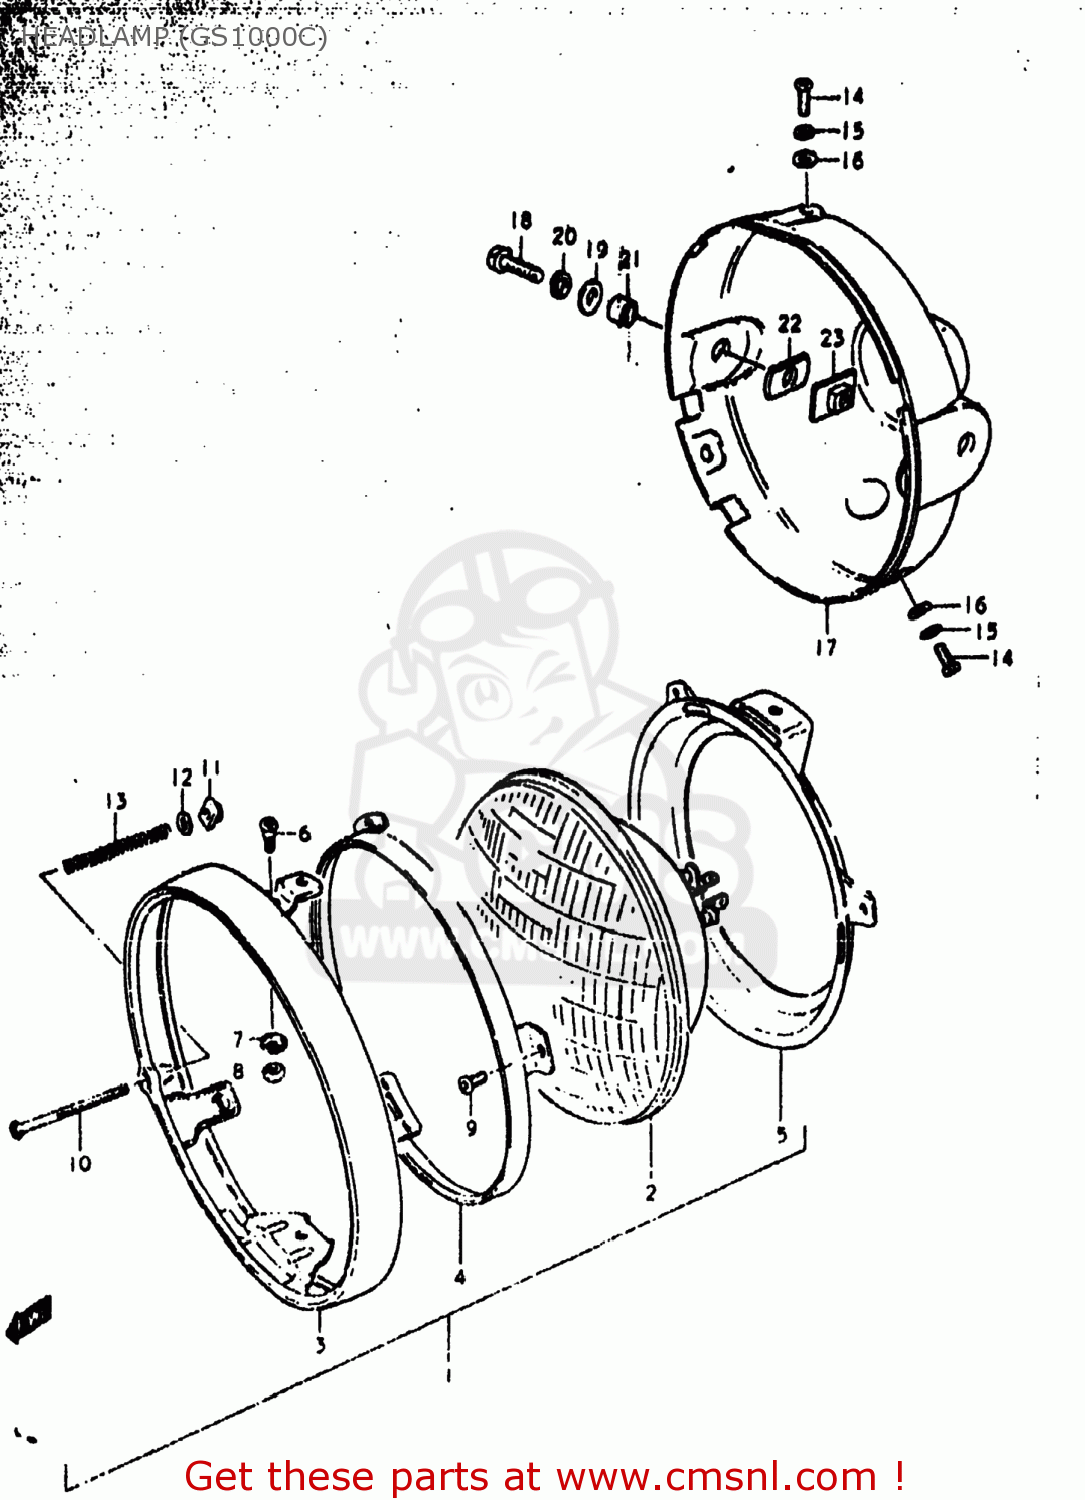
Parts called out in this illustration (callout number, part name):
1	LAMP ASSEMBLY,HEAD
2	LAMP UNIT
3	RIM
4	RETAINER
5	RING,HEADLAMP UNIT
6	SCREW
7	SPACER
8	NUT,ADJUSTING
9	SCREW
10	SCREW,HEADLAMP ADJUST
11	NUT
12	WASHER
13	SPRING,HEADLAMP ADJUST
14	SCREW
15	WASHER,LOCK
16	WASHER
17	HOUSING,HEADLAMP(BLACK)
18	BOLT
19	WASHER
20	LOCK WASHER
21	SPACER (8.8X12X7)
22	CUSHION
23	PLATE,HEADLAMP HOUSING
